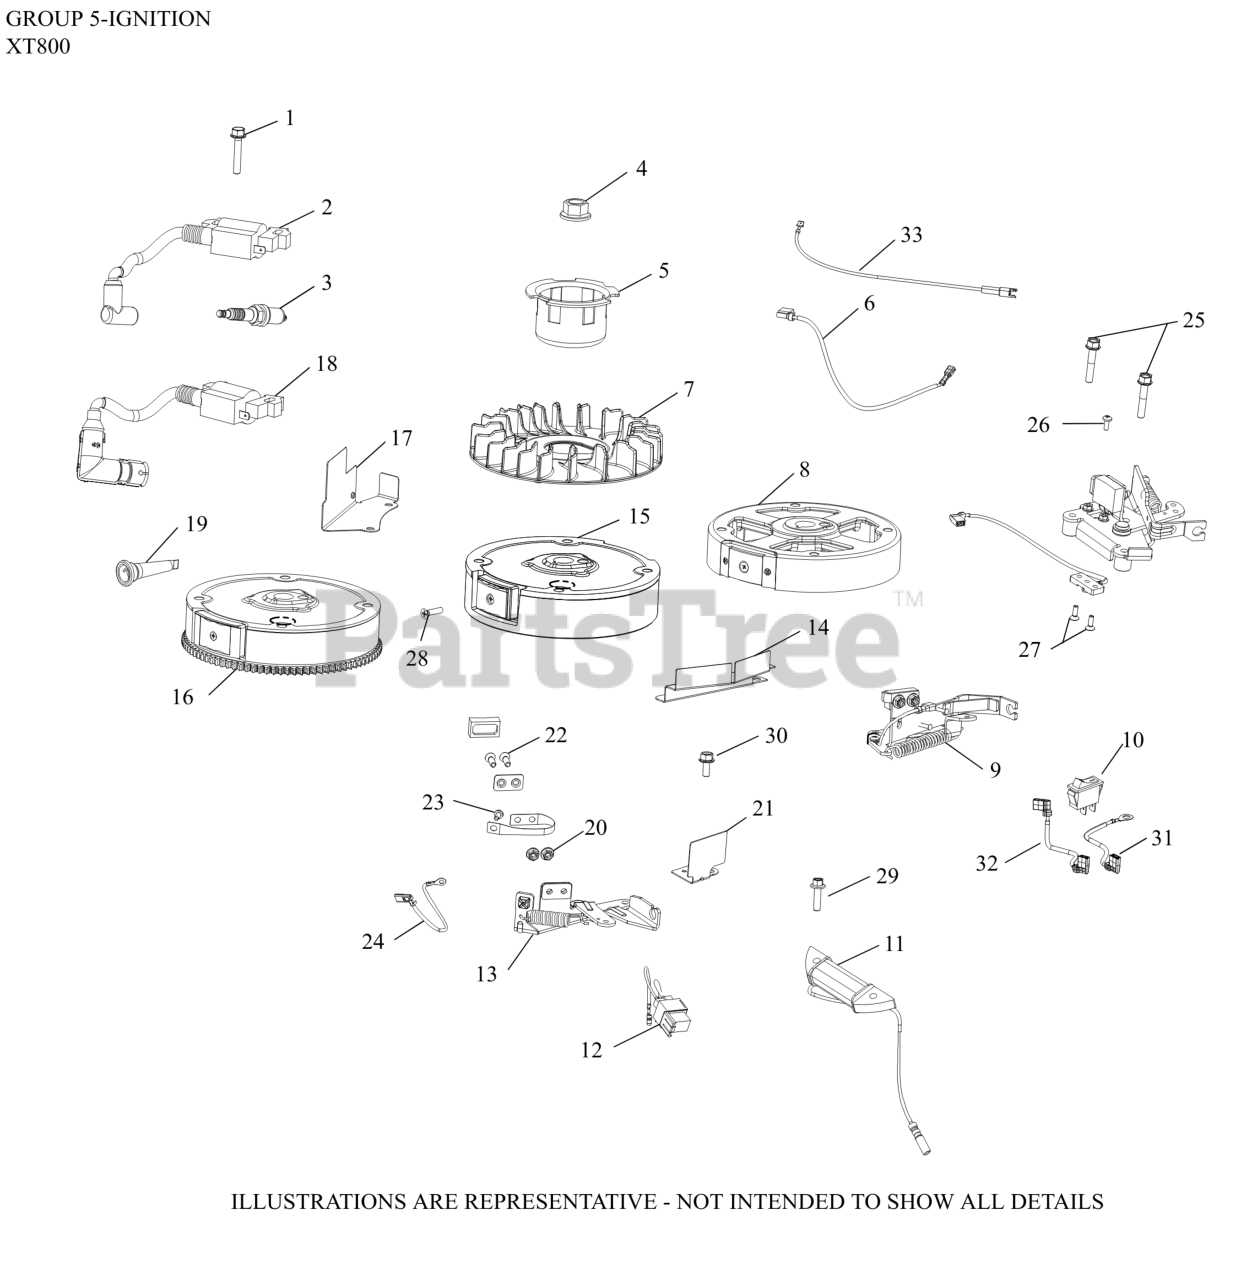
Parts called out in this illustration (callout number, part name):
1	SCREW, M6 X 25-(#25086436S)
2	MODULE IGN (#1458416S)
3	PLUG SPARK 12MM RFI
4	NUT, FLYWHEEL (W/SERRATIONS)
5	CUP, STARTER DRIVE
7	FAN, FLYWHEEL
8	FLYWHEEL ASSEMBLY
13	BRAKE, ASSEMBLY-USE 14 219 17-S
17	GUARD, FINGER
24	LEAD, KILL (BRAKE TO IGN MODULE)
